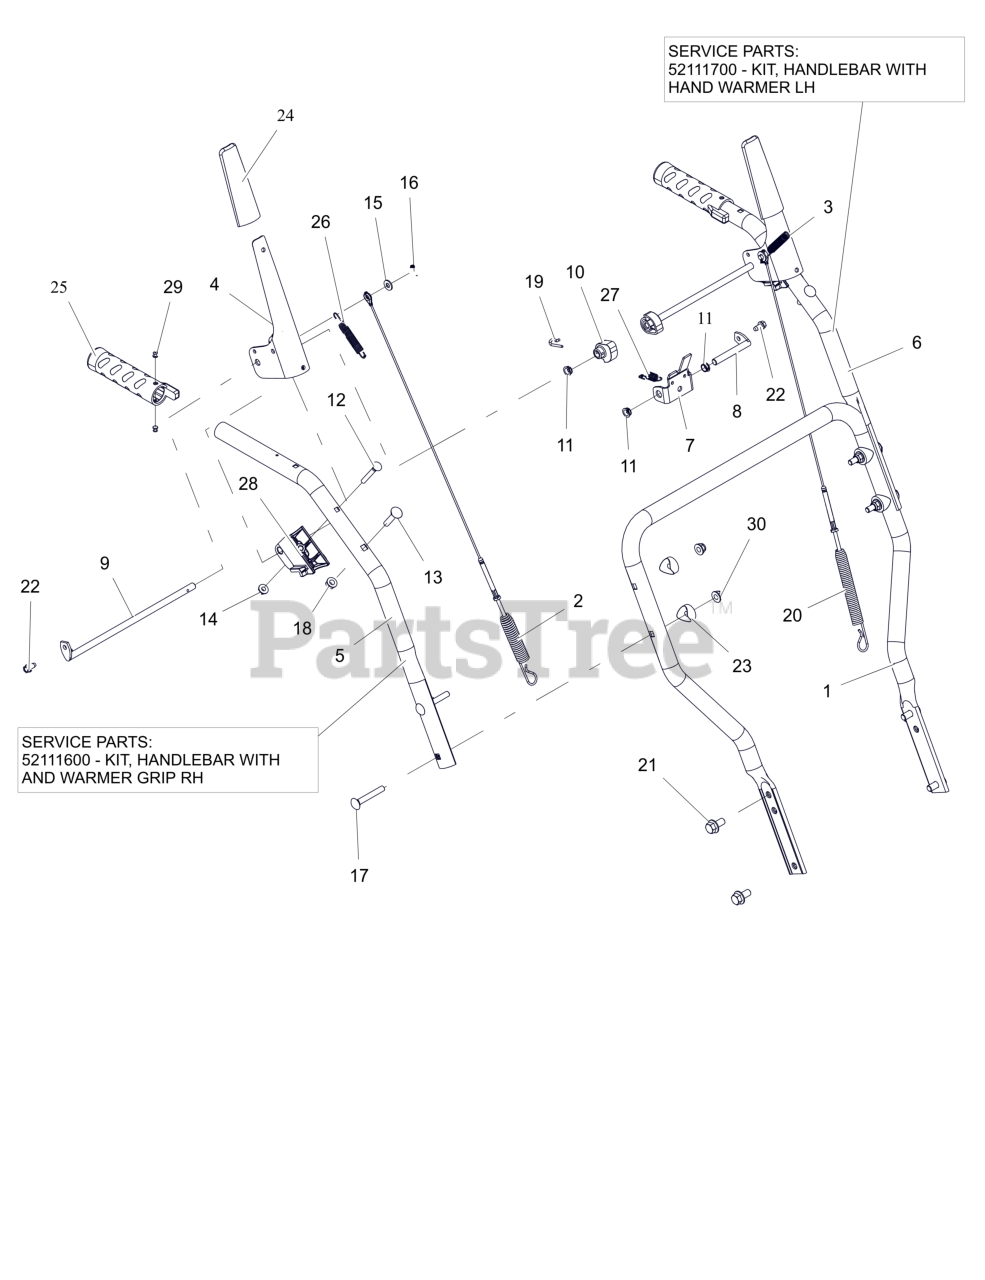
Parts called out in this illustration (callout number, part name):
1	HANDLEBAR, LOWER
2	CABLE, AUGER (DELUXE & PRO)
3	LEVER, CLUTCH-LH
4	LEVER, CLUTCH-RH
5	HANDLEBAR, UPPER - RH
5	KIT, HANDLEBAR HG RH
6	HANDLEBAR, UPPER - LH
6	KIT, HANDLEBAR HG LH
7	BRACKET, INTERLOCK ARM
8	ROD, PIVOT - INTERLOCK
9	ROD, PADDLE MOUNT - PRO
10	CAM, INTERLOCK
11	BUSHING, POLYLINER-.38 SNAPIN
12	BLT-RDHDXLSQNK .25-20X2.0 G5YZ
13	BLT,RHSN .31-18X1.50 G5 ZCC
14	NUT-LK-CTR-FLG .25-20 ZC120
15	WSHR,FLT .281X.625X.065 ZCC
16	PIN, HAIR #178 .06X.77 ZCC
17	BLT-RHSN.31-18X2.25 G5 TBZ 120
18	NUT-LK-TOP-FLG .312-18 GF ZCC
19	PIN, SPRING CLIP
20	CABLE, UPPER TRACTION
22	SCR-TAP .25-20X.50 HWH ZCC
23	SPACER, HANDLEBAR
24	COVER, PADDLE
25	GRIP, HANDLE - HEATED
26	SPRING, EXTENSION
27	SPRING-EXT .047X.438X1.45
28	BLOCK, CLUTCH PADDLE
29	RVT-POP #43 .125X.313 STL ZINC
30	NUT-NYL-FLG.31-18 GF TBZ 120WR
